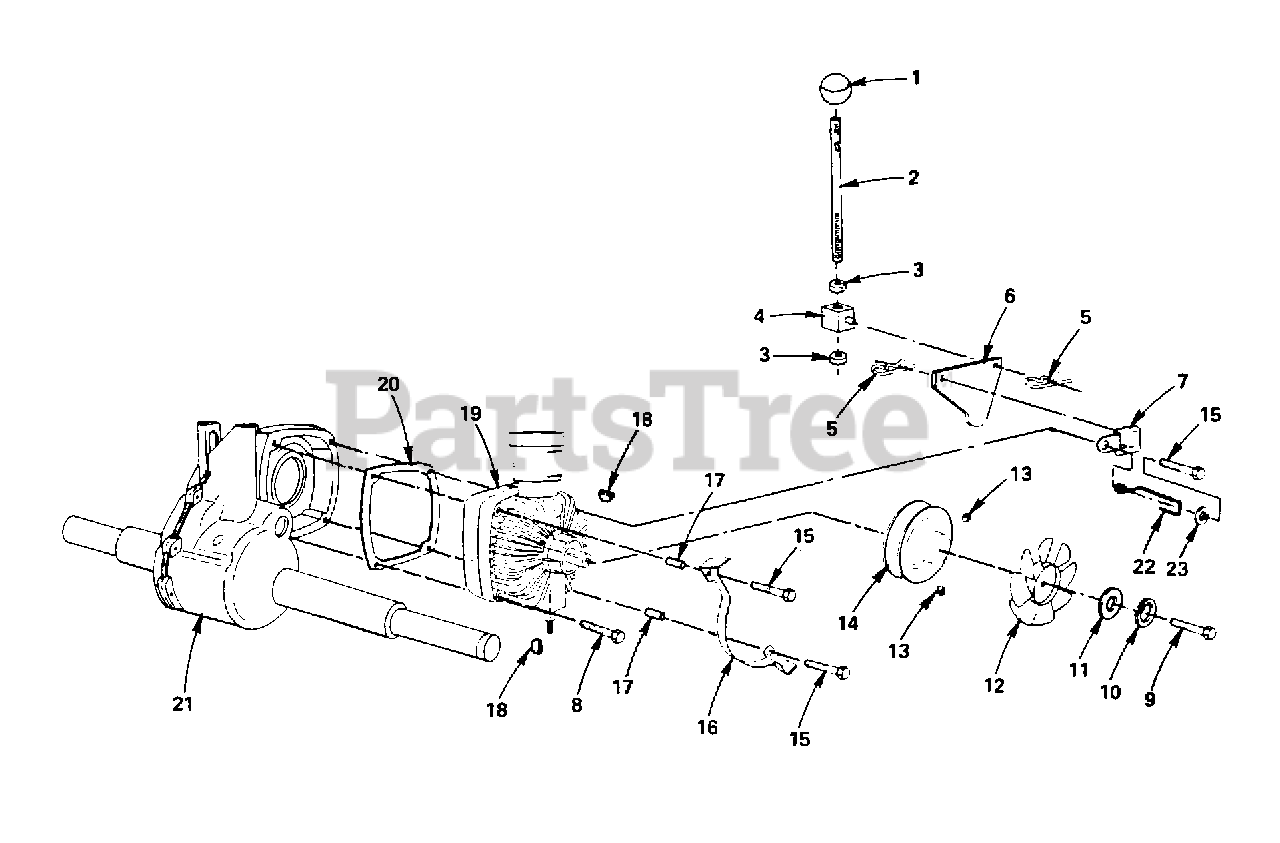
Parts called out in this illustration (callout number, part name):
1	KNOB T(3/8 HOLE)
2	ROD COAST HYT
3	NUT
4	TRUNION HYT
5	SPRING.RETAINER
6	CONTROL COAST HYT
7	BRKT ASSEM HYT
8	BOLT - HEX 3/8 - 16 X 3
9	BOLT
10	LOCKWASHER
11	WASHER
12	FAN HYDRO HYT
18	KEY T
19	PUMP HYDRO HYT
20	GASKET HYDRO HYT
23	WASHER
